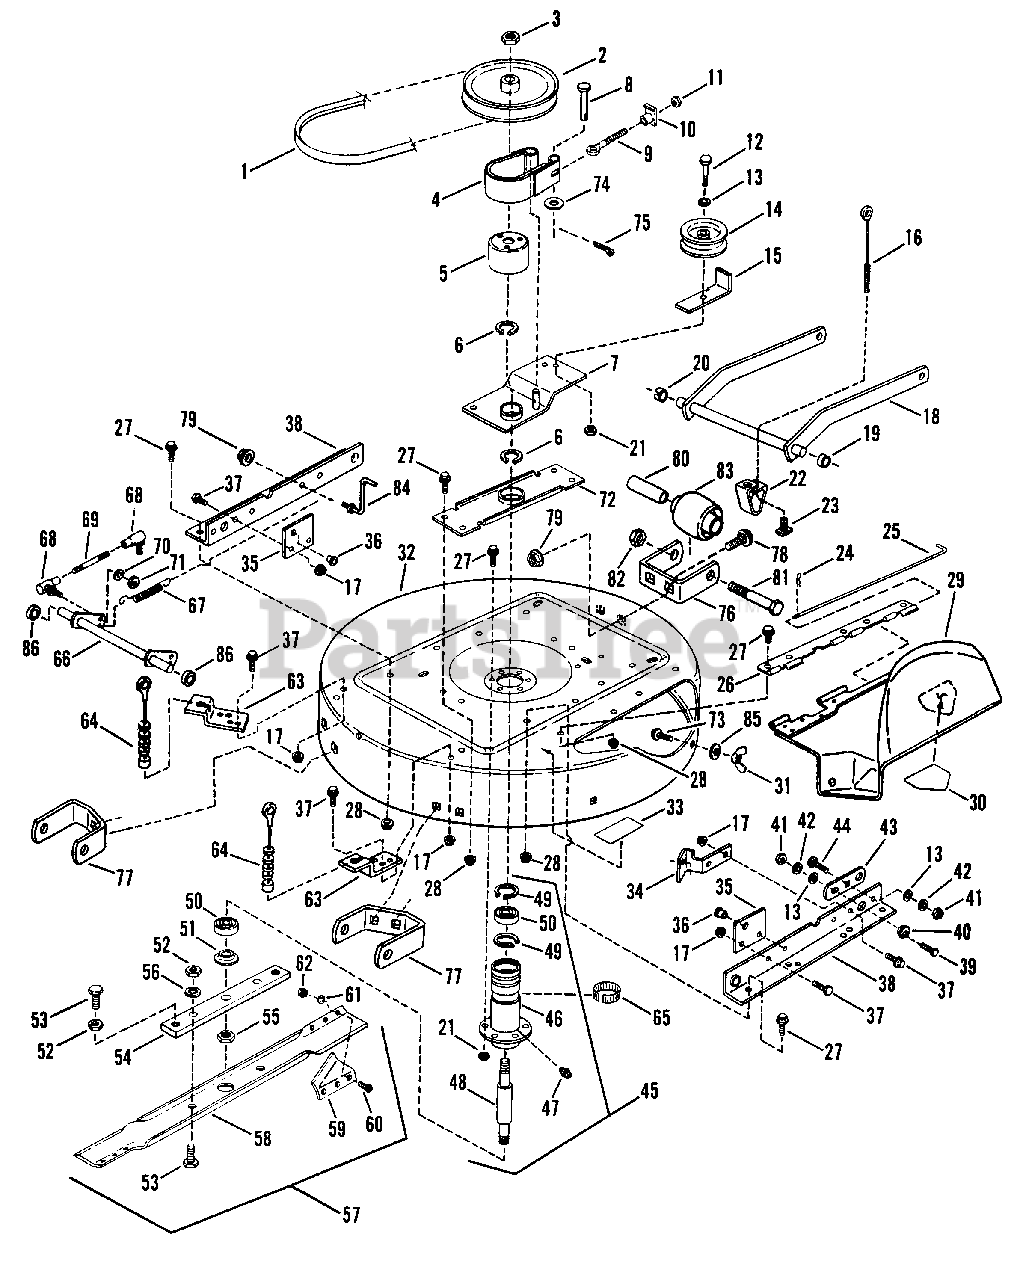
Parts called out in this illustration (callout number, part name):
1	BELT, 33" Drive Kevlar (A-59 61" OD)
2	PULLEY, 8" O.D.
3	NUT, 3/4-16 Hex Jam
4	BAND, Brake Assembly
5	DRUM, Brake
6	RING, 2" External Retaining
7	ARM, Idler
8	PIN, 1/4x1-1/4 Clevis
9	BOLT, 1/4-20 Eye
10	NUT, 1/4-20 Tee
11	NUT, 1/4-20 Hex GR 5 YZ
12	NUT, 5/16-18 Hex Center Lock
13	WASHER, 3/8 SAE
14	PULLEY, Idler, 4.12 O.D.
15	GUIDE, Belt
16	CABLE, Front Lift 6.12"
17	LOCKNUT, 5/16-18 Hex Flange
18	LIFT, Front Arm
19	RING, Red (Right Side)
20	RING, Black (Left Side)(5/8" ID x .44" Wide)
21	LOCKNUT, 3/8-24 Hex
22	BRACKET, Front Lift Hanger
23	T-NUT, 5/16-18
24	PIN, Hair 3/32" x 1.5"
25	PIN, Hinge
26	HINGE, Deflector
27	BOLT, 3/8-16x3/4 Hex Flange Lock
28	LOCKNUT, 3/8-18 Hex Flange
29	ASSEMBLY, Deflector
30	DECAL, Danger
31	WING-NUT, 5/16-18
32	DECK, Cutting, 33"
33	DECAL Caution
34	ANCHOR, Brake
35	BRACKET, Cross-Shaft
36	BEARING, Cross-Shaft Bracket
37	BOLT, 5/16-18x1/2" Hex Flange Lock
38	RAIL, Side
39	SCREW, 3/6-16x1" Hex Head Cap
40	ECCENTRIC, Leveling
41	NUT, 3/8-18 Hex
42	LOCKWASHER, 3/8 Split
43	LINK, Adjustment
44	BOLT, 3/8-16x3/4" Carriage
45	ASSEMBLY, Spindle
46	HOUSING, Spindle 5.575" Tall
47	FITTING, Lube (Press into .187" hole, no ball)
48	SPINDLE, 33" Mower Deck 8.26" Long
49	RING, Retaining EXT 1.75"
50	BEARING, Spindle
51	WASHER, Spindle
52	NUT, 1/2-20 Hex Jam
53	SCREW, 1/2-20 Hex Head Cap
54	HOLDER, Blade
55	NUT, 5/8-18 Hex Lock
56	WASHER, 1/2 Internal Tooth Lock
58	BLADE, 33" Mower Deck
59	AIR-LIFT
60	SCREW, 5/16-24x11/18 Machine
61	WASHER, 5/16-24 Internal Tooth Lock
62	NUT, 5/18-24 Hex
63	BRACKET, Rear Lift
64	CABLE, Support (4.25", 8 Spacers)
65	RING, Tolerance 2.0"
66	CROSS-SHAFT
67	SPRING
68	BALLPOINT
69	LINK, Ball Joint
70	WASHER, 1/4 Internal Tooth Lock
71	NUT, 1/4-28 Hex
72	BRACE, Spindle
73	BOLT, 5/16-18x3/4 Short Neck Carriage
74	WASHER .28 x .63 x .065 YZ
75	COTTER-PIN, 3/32x3/4"
76	BRACKET, Gage Wheel (Front)
77	BRACKET, Gage Wheel (Rear)
78	BOLT, 5/16-18x1/2" Short Neck Carriage
79	NUT, 5/16-18 Hex Flange Lock
80	SPACER .625 OD x .423 ID x 3" L
81	SCREW, 3/8-24x3-3/4 H.H.C.
82	LOCKNUT, 3/8-24 Hex
83	WHEEL Gage
84	GUIDE, Belt
85	WASHER, 5/16 Flat
86	SPACER
